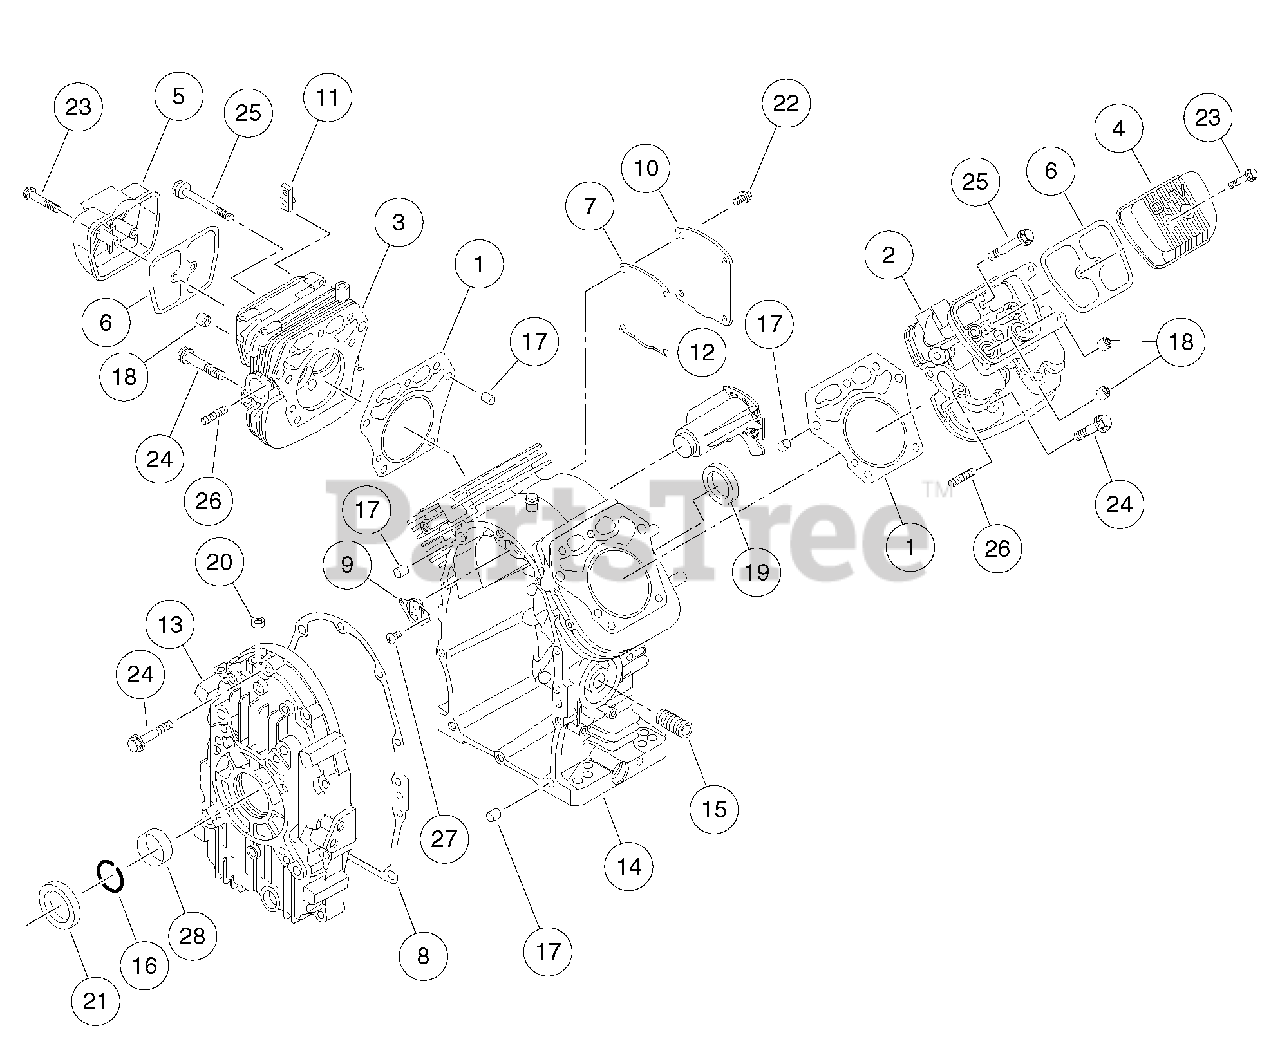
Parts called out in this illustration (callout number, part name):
1	Gasket, Head, Cyl, Fh
2	Head, Cyld 1, Fh
3	Head, Cyld 2, Fh
4	Cover, Rocker, Cyld 1, Fh
5	Cover, Rocker, Cyld 2, Fh
6	Gasket, Rocker, Cover, FH
7	Gasket, Breather, Fh
8	Gasket, Cover, Crank, Fh
9	Valve, Assy, Reed, Fh
10	Cover, Crkcase, Comp, Fh
11	Pipe, Head, Comp, Clyd, Fh
12	Pipe, Crkcase, Comp, Fh
13	Cover, Crankcase, Fh
14	Crankcase, Comp, Fh
15	Nipple, Oil Filter, Fh
16	Ring, Snap, Fh
17	Pin, Head, Fh
18	Seal, Oil, Valve, Fh
19	Seal, Oil, Crank, Rear, Fh
20	Seal, Oil, Governor, Fh
21	Seal, Oil, Crank, Front, Fh
22	Bolt, Flg, M6 X 1.0 X 12
23	Bolt, Flg, M6 X 1.0 X 40
24	Bolt, Flg, M8 X 1.25 X 50
25	Bolt, Flg, M8 X 1.25 X 75
26	Stud, M8 X 1.25, Exhaust, Fh
27	Screw, Pan, Governor, Fh
28	Bushing, Main, Fh
